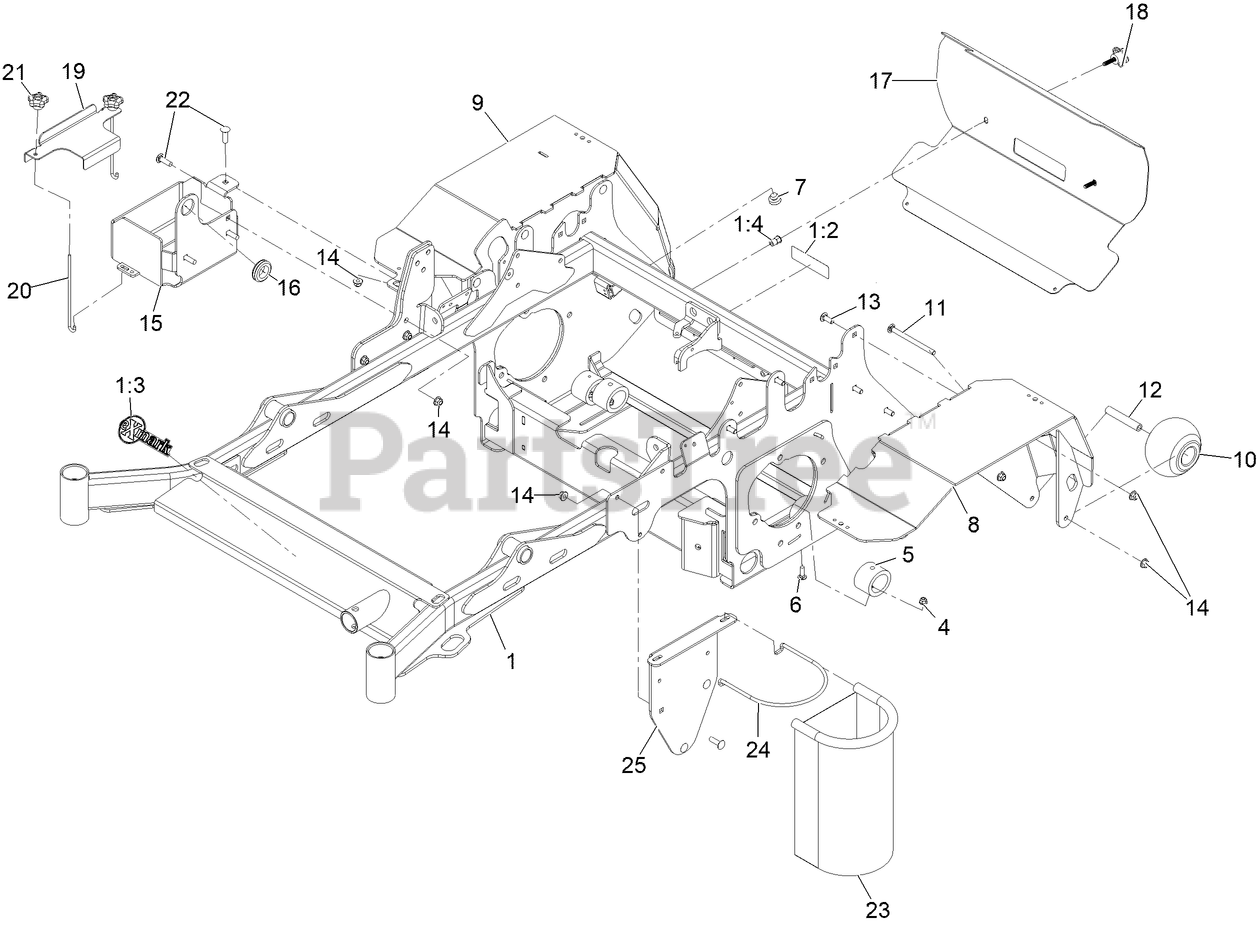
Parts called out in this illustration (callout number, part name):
1:2	DECAL-COVER, MISSING
1:3	DECAL-EXMARK LOGO
1:4	NUT-CLINCH
4	NUT-HF, NI
5	BUMPER-ISOLATOR
6	BOLT-CARR
7	BUMPER-RUBBER
8	FENDER-LH WELDT
9	FENDER-RH WELDT
10	ROLLER-SCALP, ANTI
11	BOLT-CARR
12	SPACER- ROLLER
13	SCREW-CARR
14	NUT-HF, NI
15	BATTERY TRAY
16	GROMMET
17	GUARD-REAR FOOT
19	BRACKET-BATTERY HOLD DOWN
20	BOLT-HOLDDOWN
21	KNOB-HANDLE
22	Bolt-Carriage 3/8-16 X 1 1/4
23	BAG-TRASH
24	ROD-BAG, TRASH
25	BRACKET-TRASH BAG MOUNT
